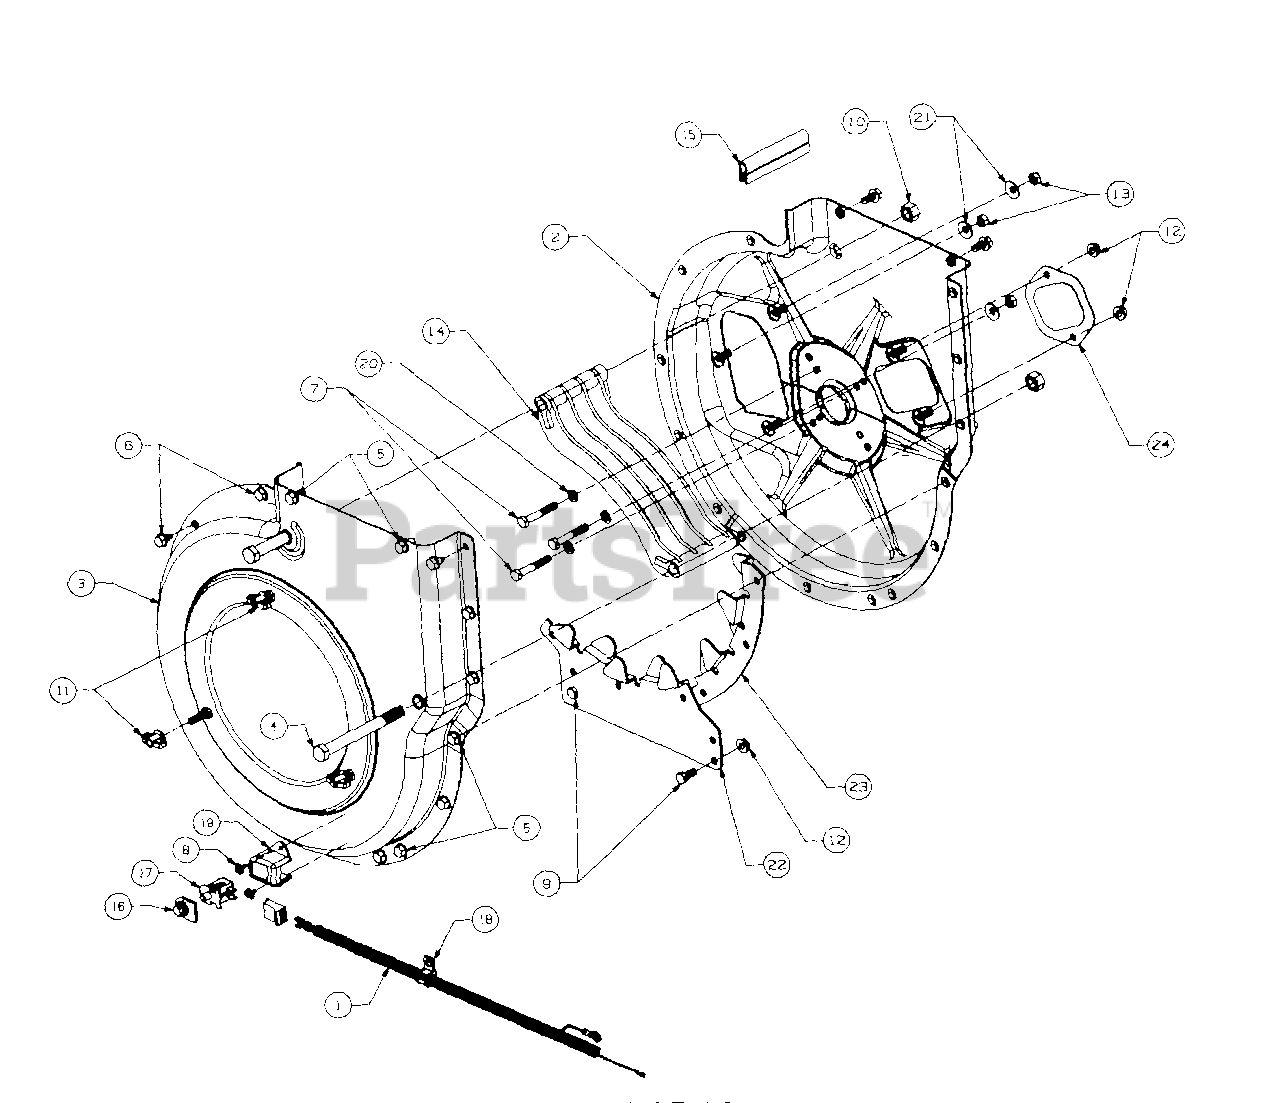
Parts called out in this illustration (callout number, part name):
1	HARNESS-CHIPPER VAC
4	SCREW-HEX
5	SCREW-HEX SELF TAP
6	SCREW-HEX SELF TAP
7	SCREW-HEX
8	SCREW-HEX SELF TAP
9	SCREW-HEX
10	NUT-HEX LOCK
12	NUT-HEX LOCK
13	NUT-HEX (GR 5)
14	SCREEN
15	SEAL-RUBBER
16	COVER-SWITCH
17	SWITCH
18	CLAMP
19	COVER SWITCH
20	WASHER-LOCK
21	WASHER-BELL
